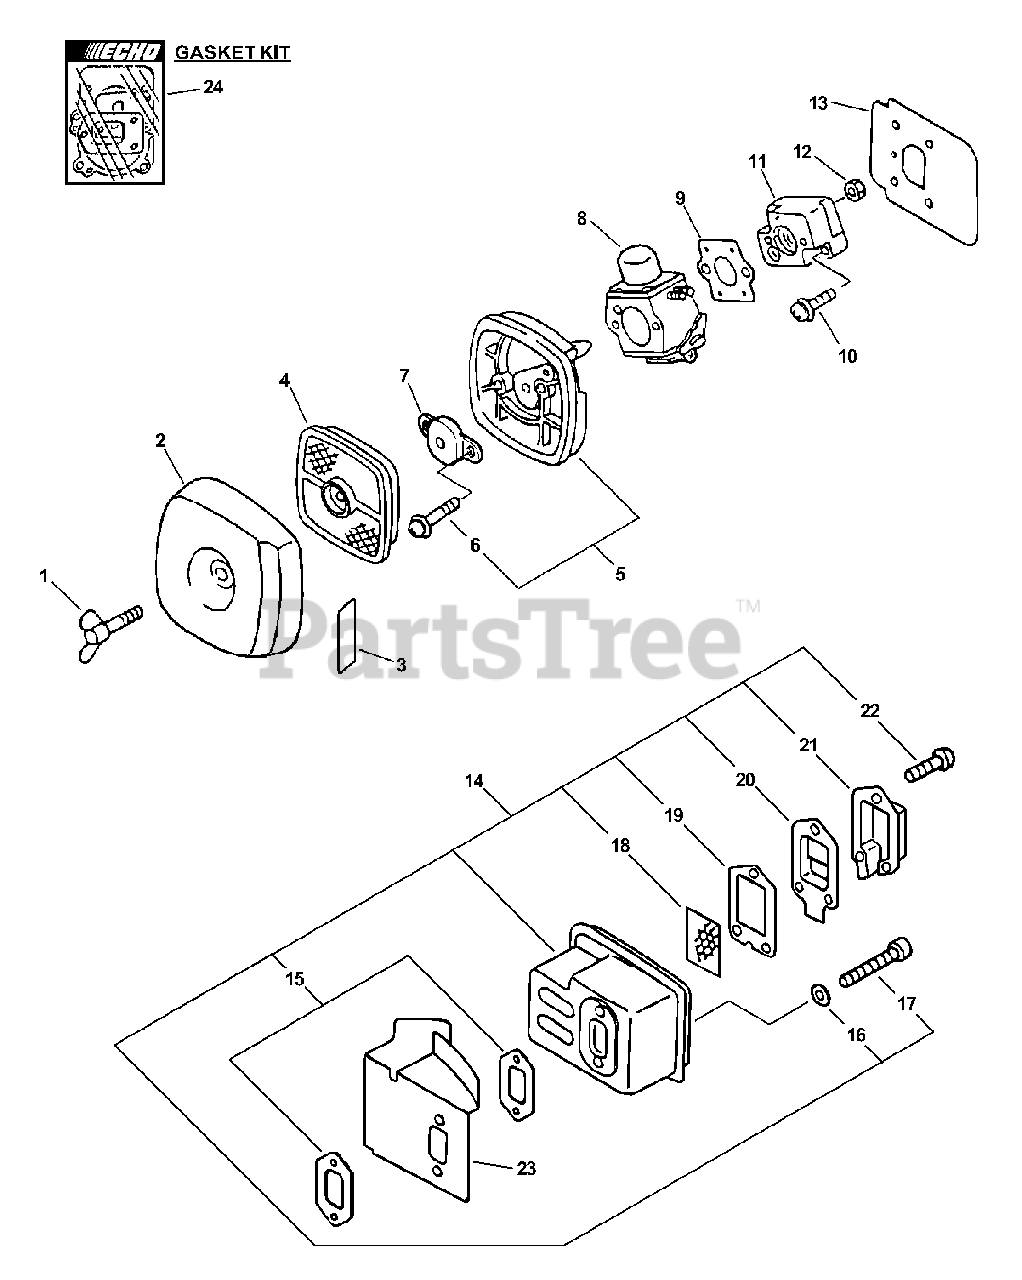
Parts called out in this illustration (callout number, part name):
1	BOLT, WING 5×20
2	COVER, AIR FILTER - GRAY
3	LABEL, CHOKE
4	FILTER, AIR - SINGLE LAYER
5	CASE, AIR FILTER - GRAY
6	SCREW 5×65
7	PLATE, PREVENT
8	CARBURETOR - C1U-K54
9	GASKET, INTAKE
10	SCREW 5×20
11	INSULATOR, INTAKE
12	NUT M5
13	HEAT SHIELD, INTAKE
14	MUFFLER ASSY
15	GASKET, EXHAUST
16	WASHER, FLAT 5.5×10×0.8
17	BOLT M5×50
18	SCREEN, SPARK ARRESTER
19	GASKET, EXHAUST
20	GUIDE, EXHAUST
21	GUIDE, EXHAUST - INNER
22	SCREW 4×10
23	COVER, MUFFLER
24	GASKET KIT
